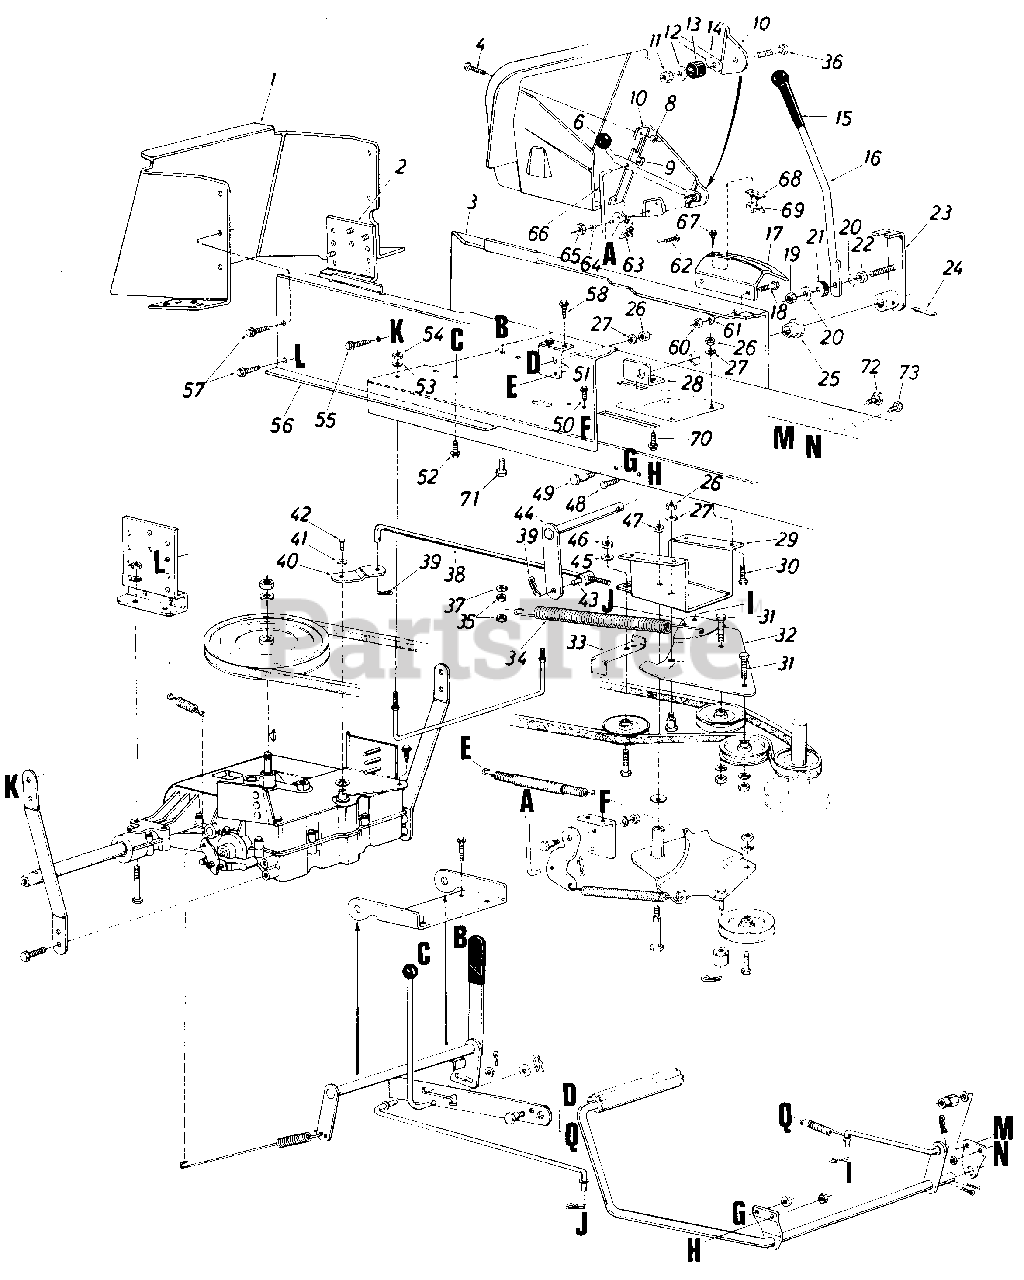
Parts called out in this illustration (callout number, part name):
1	Hitch Piate
2	Transaxle Support Bracket
3	Side Panel Upper Frame
4	Truss. Mach. Scr. 1/4-20 x .50" Lg.
6	Knob
8	Hex Sems Nut 1/4-20 Thd.
9	Push Cap 1/4" Rod
10	Deck Clutch Control Brkt.
11	Hex Cent. L-Nut 1/4-20 Thd.
12	Fl-Wash. .281" I.D. x .734" O.D. x .063 Thk.
13	Rubber Wash. .330" I.D. x .87" O.D. x .32 Thk.
14	Blade Clutch Lever
16	Shift Lever
17	Shift Bracket
18	Hex Bolt 5/16-18 x .62" Lg.
19	Hex Cent. L-Nut 5/16-18 Thd.
20	Fl-Wash. .344" I.D. x .875" O.D. x .063 Thk.
21	Rubber Wash. .330" I.D. x .87" O.D. x .32 Thk.
22	Hex Nut 5/16-18 Thd.
23	Handle Mount Brkt. Ass'y.
24	Spring Pin Spiral 1/4" Dia. x 1.5" Lg.
25	Plastic Hex Bearing .625" I.D.
26	Hex Nut 5/16-18 Thd.
27	L-Wash. 5/16" I.D.
28	Speed Control Shaft Brkt.
29	Transaxle Clutch Support Brkt.
30	Hex Bolt 5/16-18 x 2.50" Lg.
31	Hex Bolt 3/8-16 x 1.25" Lg.
32	Idler Bracket Ass'y.
35	Hex Cent. L-Nut 1/4-20 Thd.
36	Hex Bolt 1/4-20 x 1.25" Lg.
37	L-Wash. 1/4" I.D.
38	Shift Link
39	Hairpin Cotter 3/8"
40	Shifter Bracket
41	Belleville Wash. .25" I.D. x .375" O.D.
42	Hex Bolt 1/4-28 x .62" Lg.
43	Pivot Bushing
44	Speed Control Shaft Ass'y.
45	Fl-Wash. .385" I.D. x .87" O.D. x .060 Thk.
46	Hex Cent. L-Nut 3/8-24 Thd.
47	Hex Cent. L-Nut 3/8-16 Thd.
48	Hex Bolt 3/8-16 x .62" Lg.
49	Shoulder Bolt .500" Dia. x .340" Lg. (3/8-16)
50	Hex Thd. Rolling Scr. 1/4-20 x .50" Lg.
51	Parking Brake Cam Mtg. Brkt.
52	Hex Thd. Rolling Scr. 1/4-20 x .50" Lg.
53	L-Wash. 1/4" I.D.
54	Hex Nut 1/4-20 Thd.
55	Hex Wash. Hd. TT-Tap Scr. 3/8-16 x .5" Lg.
56	Side Panel Upper Frame R.H.
57	Hex Thd. Rolling Scr. 5/16-24 x .50" Lg.
58	Hex Thd. Rolling Scr. 1/4-20 x.50" Lg.
60	Hex Nut 5/16-18 Thd.
61	L-Wash. 5/16" I.D.
62	Truss Mach. Scr. #10-24 x .50" Lg.
63	Safety Switch
64	Ext. L-Wash. #10 I.D.
65	Hex Nut #10-24 Thd.
66	Deck Control Rod
67	Hex Wash. Hd. Scr. #8 x .50" Lg.
68	Insulator Nut Plate
69	Spring Switch
70	Hex Wash. Hd. AB-Tap Scr. 5/16 x .75" Lg.
71	Hex Wash. Hd. TT-Tap Scr. 1/4 x 1.5" Lg.
72	Shld. Bolt .498" Dia. x .34"
73	Hex Bolt 3/8-16 x .62" Lg.
